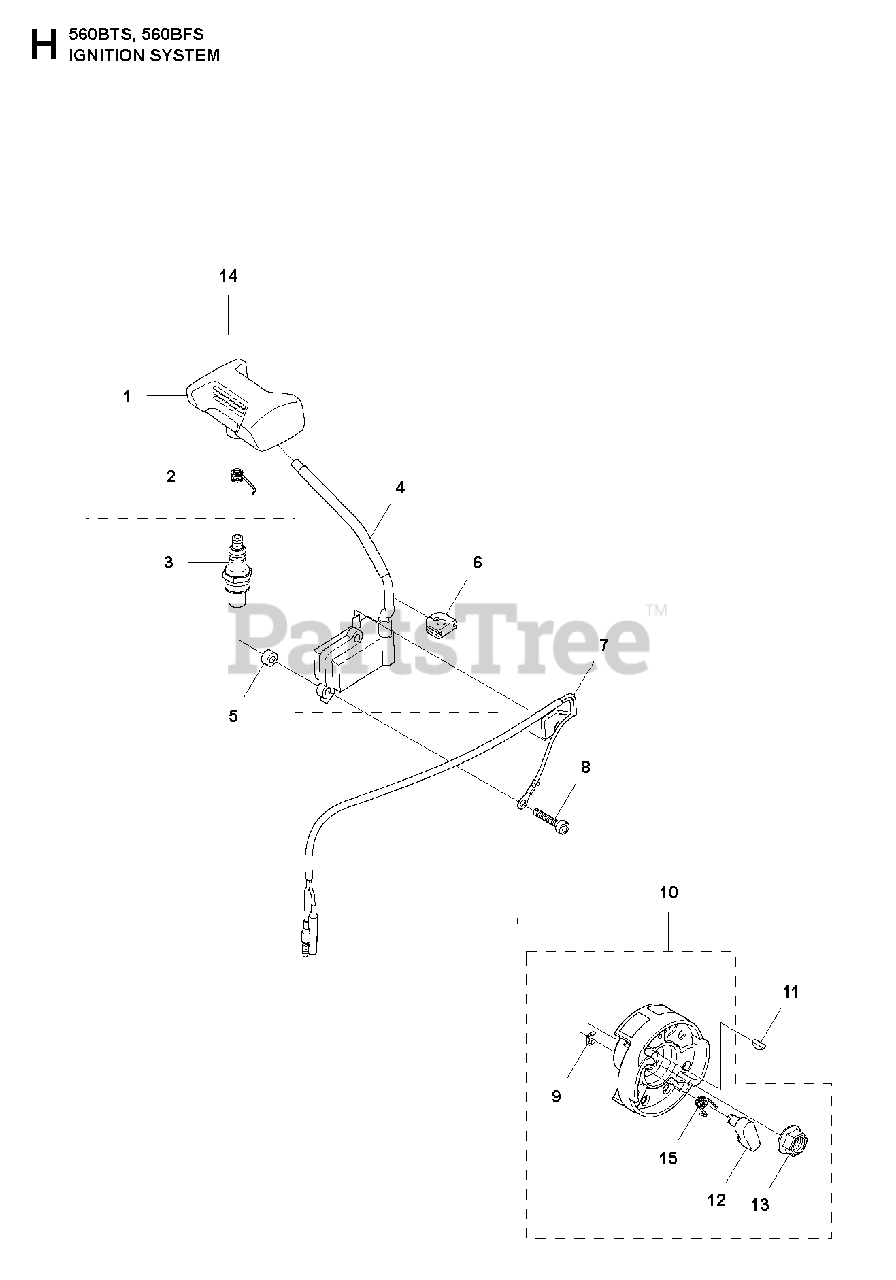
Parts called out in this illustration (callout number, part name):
1	SPARK PLUG CAP
2	SPRING PLUG
3	SPARK PLUG NGK CMR7H
4	TUBE
5	SPACER
6	GROMMET
9	RING
10	ROTOR ASSY
12	RATCHET
13	NUT
14	COIL ASSY
15	SPRING
